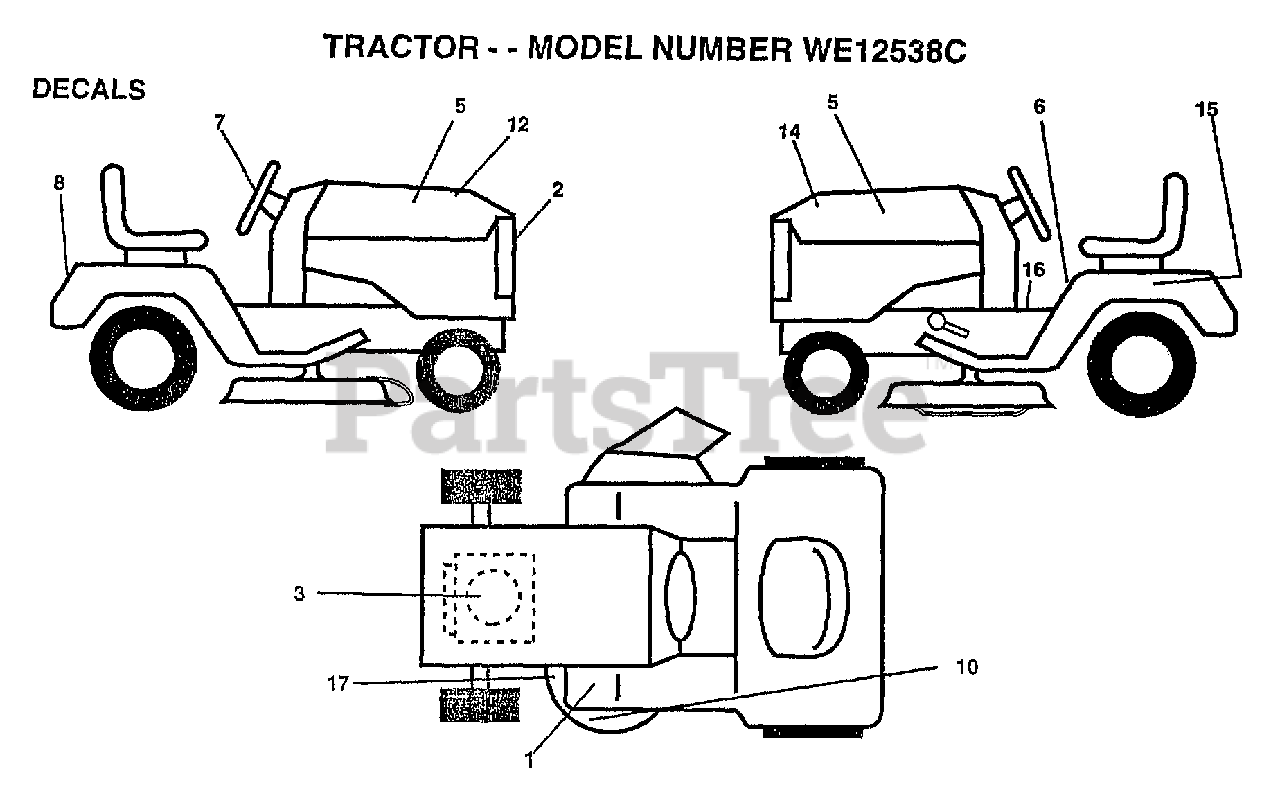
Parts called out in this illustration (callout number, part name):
2	"DECAL GRILLE,LENS"
3	DECAL, HP ENGINE
5	"DECAL.PANEL,SIDE"
6	"DECAL DANGER,FEND"
7	"DECAL INS,STRG WH"
8	DECAL-FENDER
9	DECAL CHASSIS SPEED DECK
11	DECAL.DANGER.CUTF
12	"DECAL HOOD,RH"
14	DECAL HOOD LH
15	DECAL.BATRY.3-3908
16	"DECAL DASH,OPER."
17	DECAL
18	DECAL.EURO.ST.CE.
